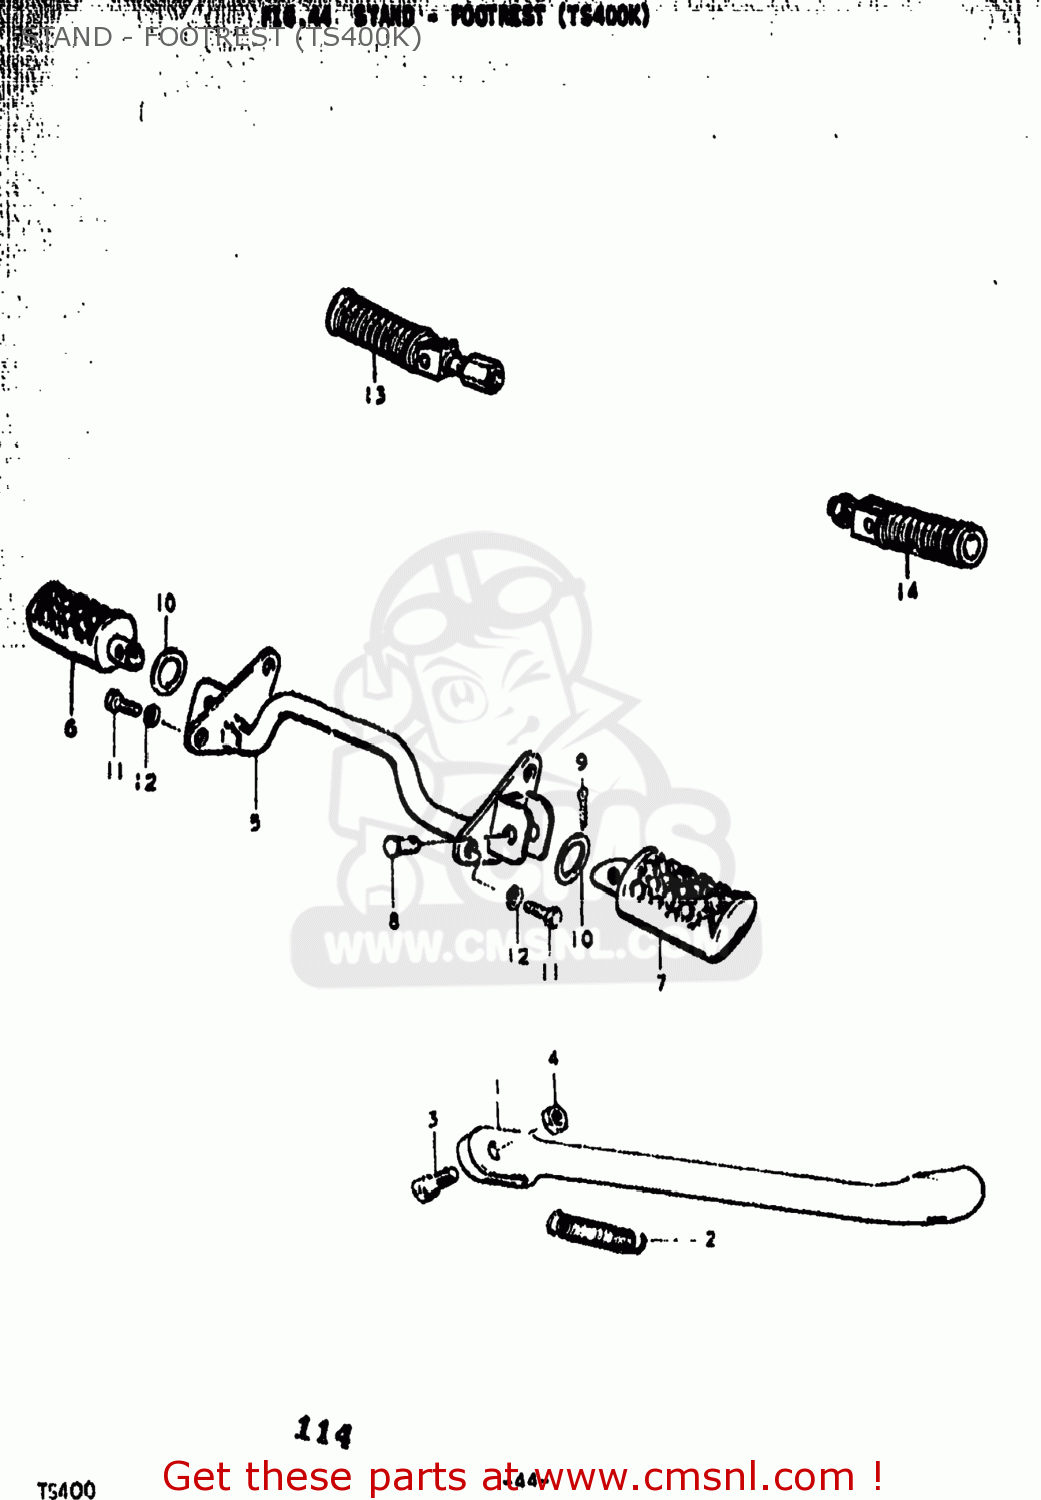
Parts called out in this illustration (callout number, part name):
1	STAND,SIDE
2	SPRING
3	BOLT(10X30)
4	NUT
5	BAR,FRONT FOOTREST
6	RUBBER,FOOTREST,RIGHT
7	RUBBER,FOOTREST,LEFT
8	PIN
9	PIN
10	SECOND GEAR INNER THRUST WASHER
11	BOLT
12	WASHER,LOCK,8.
13	FOOTREST ASSEMBLY,REAR
14	FOOTREST ASSEMBLY,REAR
